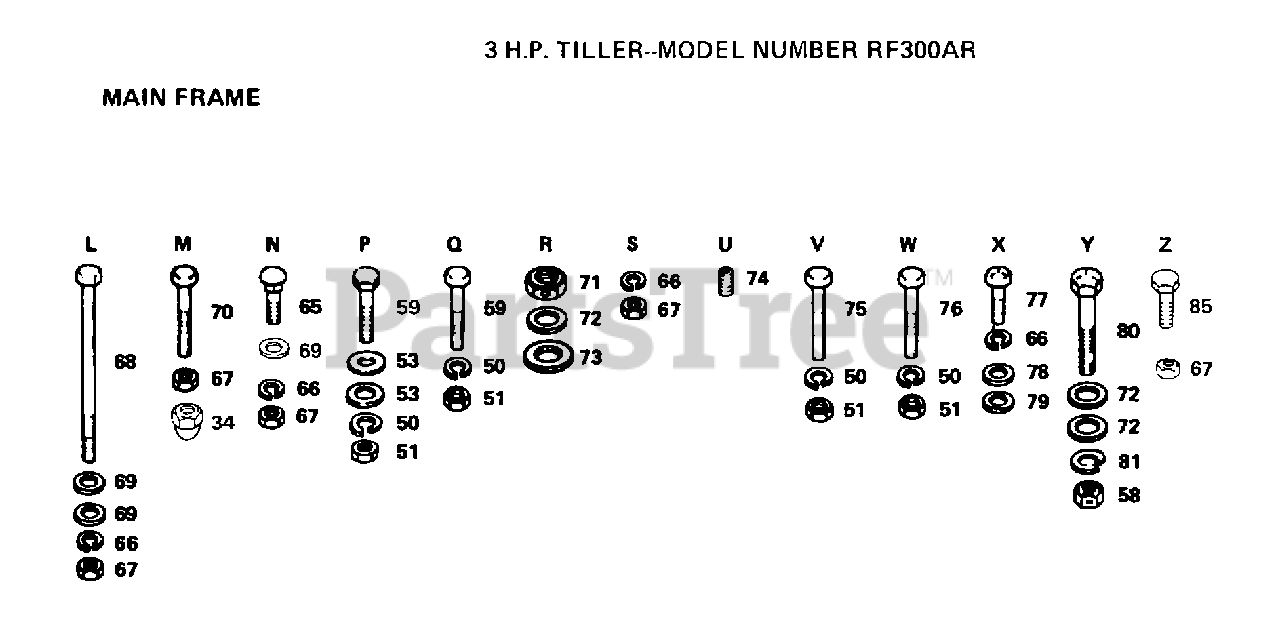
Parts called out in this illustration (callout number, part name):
34	NUT-CAP TI
50	LOCKWASHER
51	NUT.HEX.5/16-18
53	WASHER
58	GRIPCO NUT
65	BOLT
66	LOCKWASHER
69	WASHER
70	BOLT
72	WASHER
75	BOLT.HEX.5/16-1.5
77	BOLT
78	WASHER
79	WASHER
80	BOLT.3/8-24X3.75
81	LOCKWASHER
